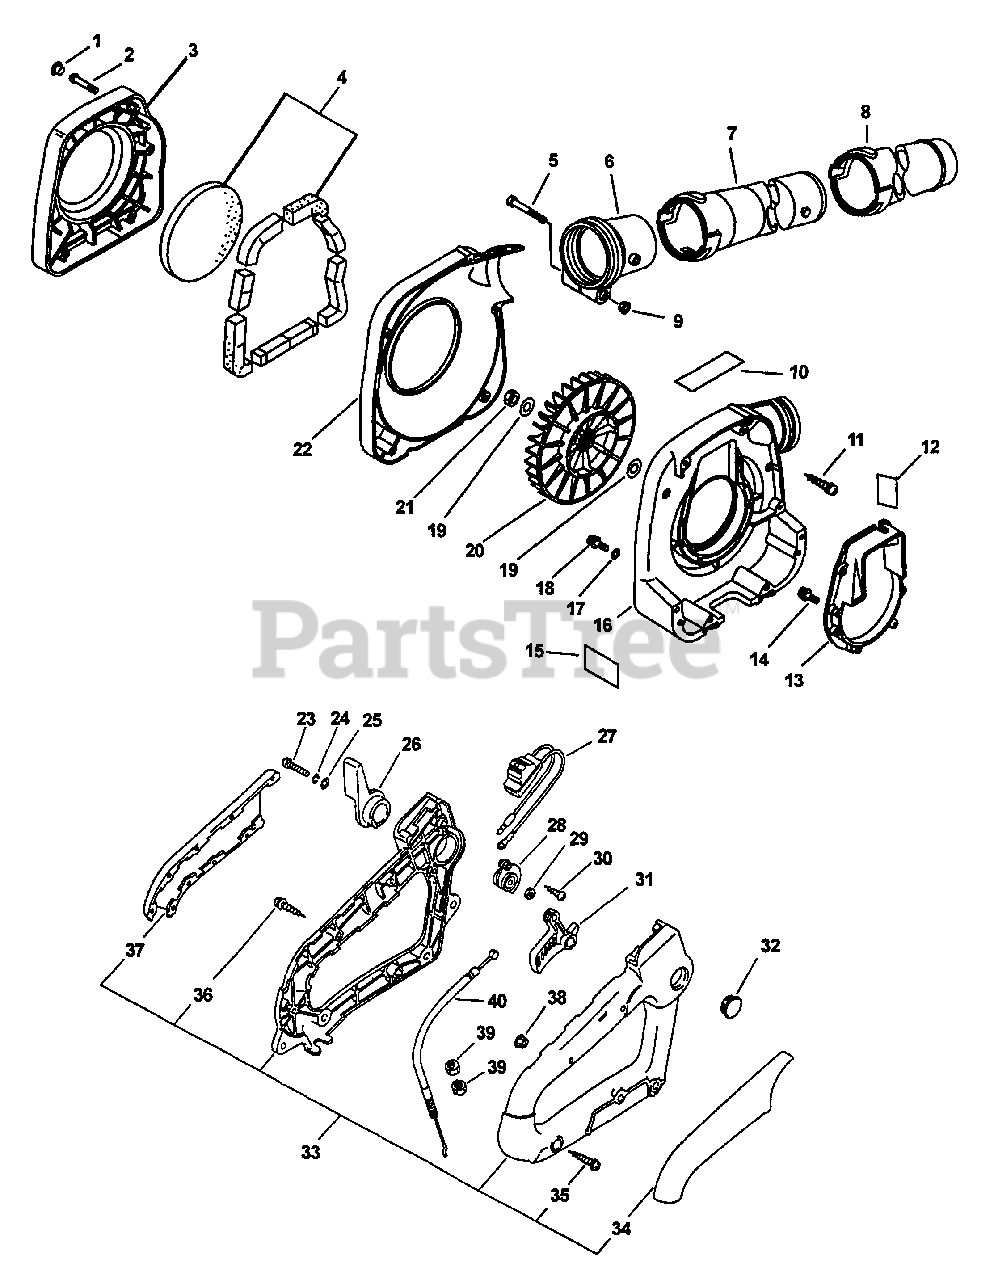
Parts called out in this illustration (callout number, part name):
1	PLUG
2	SCREW - 5X20
3	GUARD, DEBRIS
4	FOAM PAD ASSY
5	SCREW - 5X60
6	ADAPTER, TUBE
7	TUBE, BLOWER - STRAIGHT
8	TUBE, BLOWER - NOZZLE
9	NUT - 5 -- FLANGE
10	LABEL - NOISE
11	SCREW - 5X30
12	LABEL - CAUTION -- SPANISH
13	BRACKET, ENGINE
14	SCREW - 4X18
15	LABEL - HOT SURFACE
16	COVER, FAN - RIGHT
18	SCREW - 4X22
19	WASHER - 8
20	FAN
22	COVER, FAN - LEFT
23	SCREW - 6X20
24	LOCKWASHER - 6
25	WASHER - 6
26	CONTROL, THROTTLE
27	IGNITION SWITCH ASSY
28	BRACKET, THROTTLE
29	LOCKNUT - 6
30	SCREW - 4X10
31	TRIGGER, THROTTLE
33	HANDLE SET - REAR
34	GRIP, HANDLE - RIGHT
35	SCREW - 5X35
36	SCREW - 4X22
37	GRIP, HANDLE - LEFT
38	NUT - 5 -- FLANGE
40	CABLE, THROTTLE
